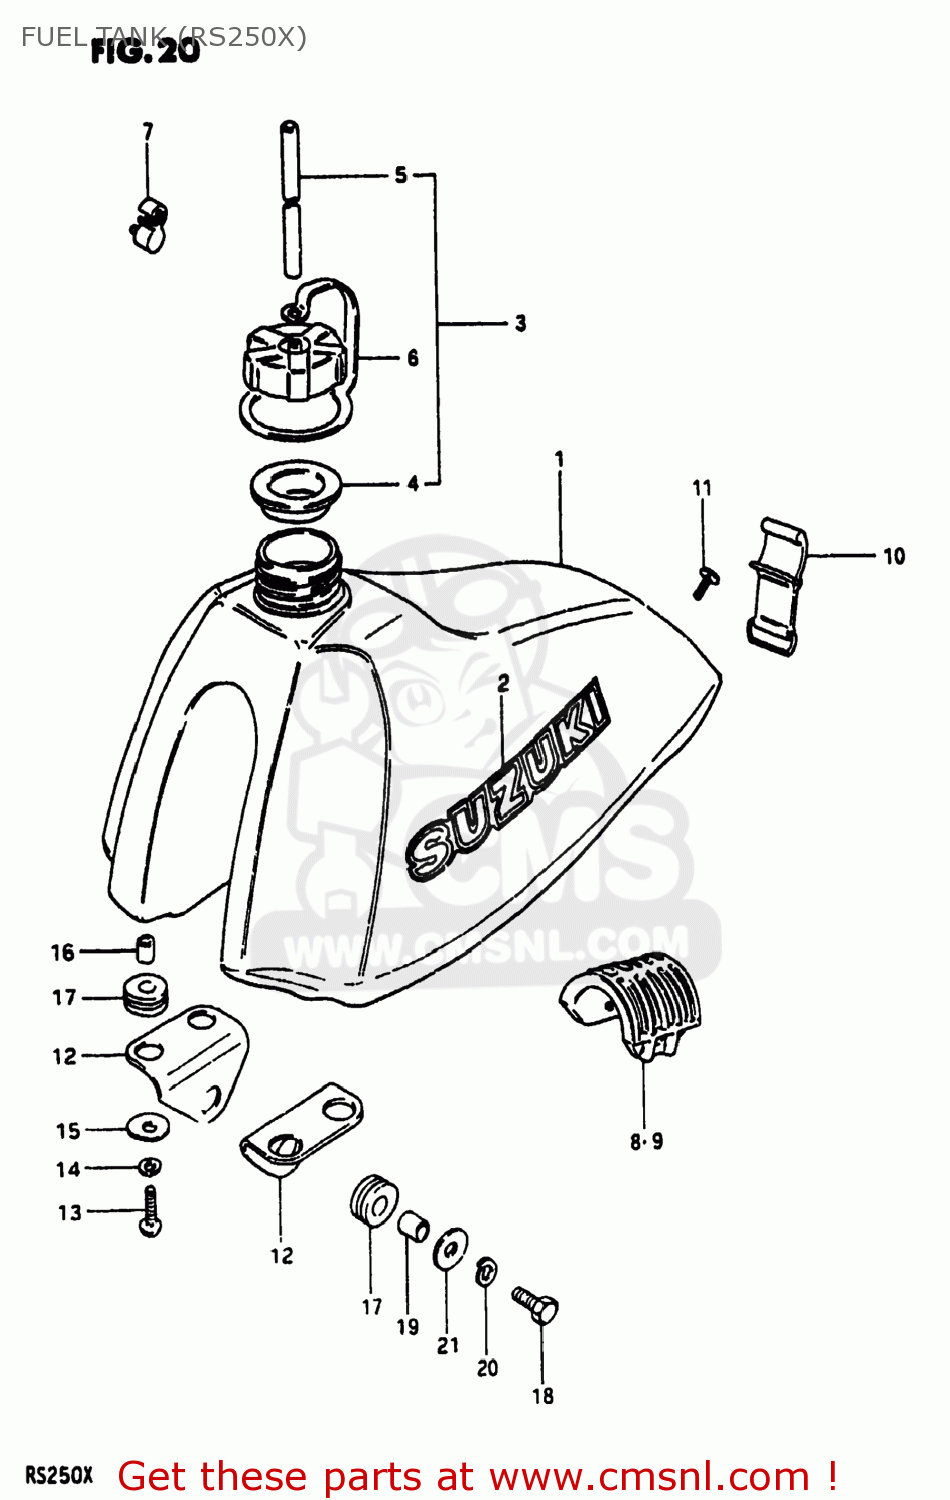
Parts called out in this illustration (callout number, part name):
1	TANK ASSEMBLY,FUEL
2	EMBLEM
3	CAP SET,FUEL TANK
4	GASKET,FUEL TANK CAP (NAS)
5	HOSE
6	BAND,FUEL TANK CAP
7	CLAMP,BREATHER HOSE
8	CUSHION,FUEL TANK
9	CUSHION,FUEL TANK
10	BAND
11	SCREW(6X18)
12	BRACKET,FUEL TANK,LOWER
13	SCREW
14	LOCK WASHER
15	WASHER (6.5X24X1.6)
16	SPACER(6.8X12X11)
17	CUSHION
18	BOLT (8X30)
19	SPACER (8.8X12X11)
20	LOCK WASHER
21	WASHER (8.2X24X1.6)
